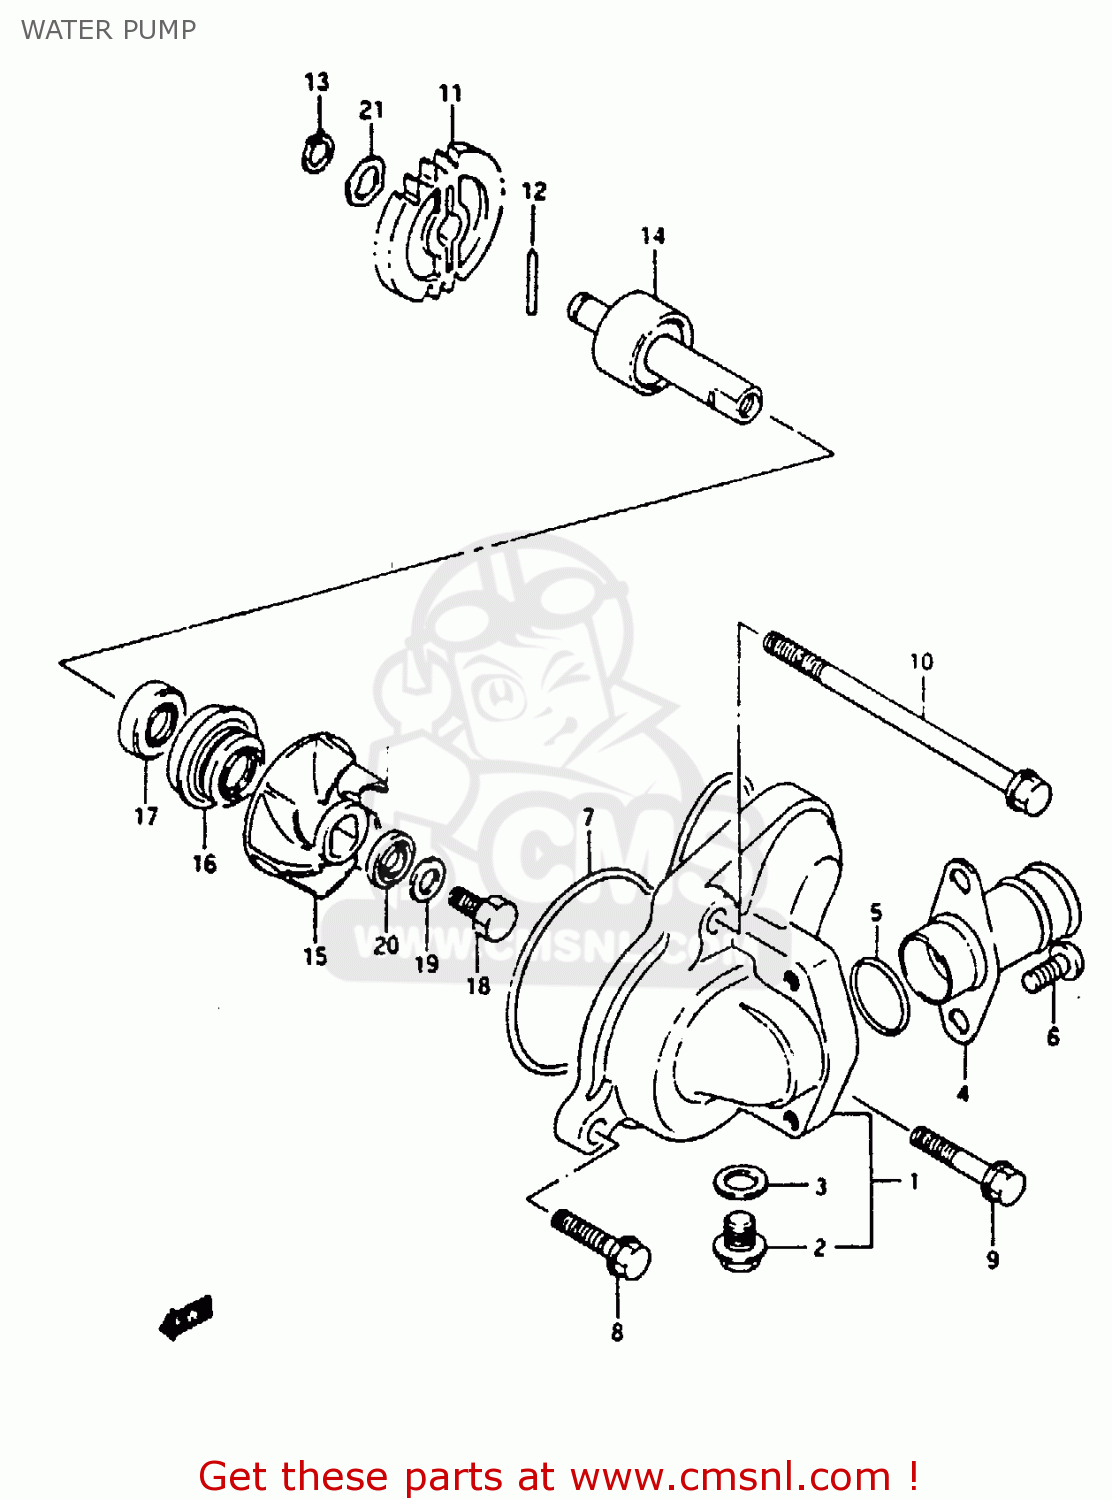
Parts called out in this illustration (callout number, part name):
1	CASE,WATER PUMP
2	BOLT,DRAIN
3	GASKET 8.2X14X1 (NAS)
4	CONNECTOR, WATER INLET
5	O RING(D:1.9,ID:18.8)
6	SCREW
7	O RING,WATER PUMP CASE
8	BOLT
9	BOLT
10	BOLT
11	GEAR,WATER PUMP DRIVEN
12	PIN(2.5X19.8)
13	CIRCLIP,10MM
14	SHAFT,WATER PUMP
15	IMPELLER,WATER PUMP
16	SEAL,MECHANICAL
17	SEAL,OIL(10X20X5)
18	BOLT(6X13)
19	WASHER
20	GASKET(6X15X2.2) (NAS)
21	WASHER
